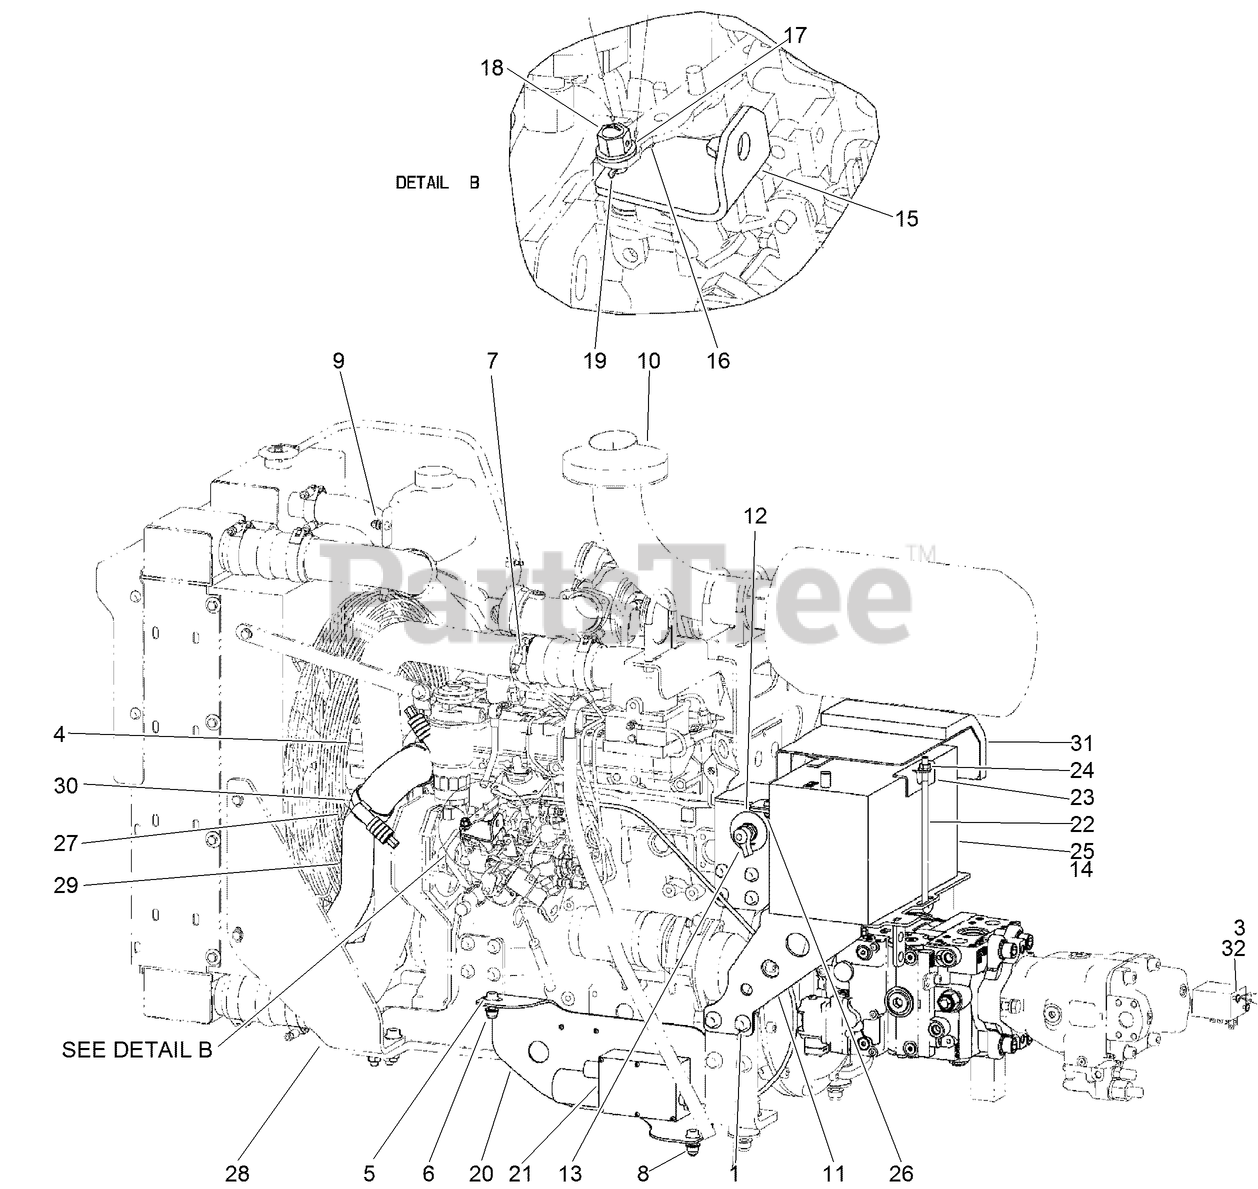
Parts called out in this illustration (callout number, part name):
1	SCREW, METRIC FLANGE w/BODY-M12 x 30
3	SCREW - PHd Sltd # 10-24 x 0.75 CST ZND
4	SCREW-FLANGE, METRIC
7	NUT - M10, Class 10, PHC
8	NUT-FLANGE, NYLOCK
9	HOSE - Upper Radiator
10	TUBE-EXHAUST (W/ SEAL PLATE)
11	ASSEMBLY - Battery Mount
12	FACEPLATE-BATTERY, ON/OFF
13	SWITCH-BATTERY (1000 AMP)
14	BATTERY (purchase locally)
15	BRACKET - Throttle
16	BOLT - Thd to Hd M6 x 12 GR8 ZND
17	WASHER-FLAT
18	NUT - Cable Retaining
19	PIN - Cotter .062 x 1.00 in ZN
20	BRACKET - Throttle
21	ACTUATOR-THROTTLE
22	BOLT-HOLDDOWN, BATTERY
23	ANGLE-HOLDDOWN, BATTERY
24	NUT-Serr Flg 3/8-16 UNC GR5 ZND
25	BATTERY - Cover
26	SCREW-HHF
27	ELBOW - Rubber, 2 Dia
28	HOSE-CONNECTING
29	TUBE - Lower Radiator
30	CLAMP-TORQUE, CONSTANT
31	SHIELD-HEAT
32	WASHER - 0.203 x 0.469 x 0.049 in CST ZND
